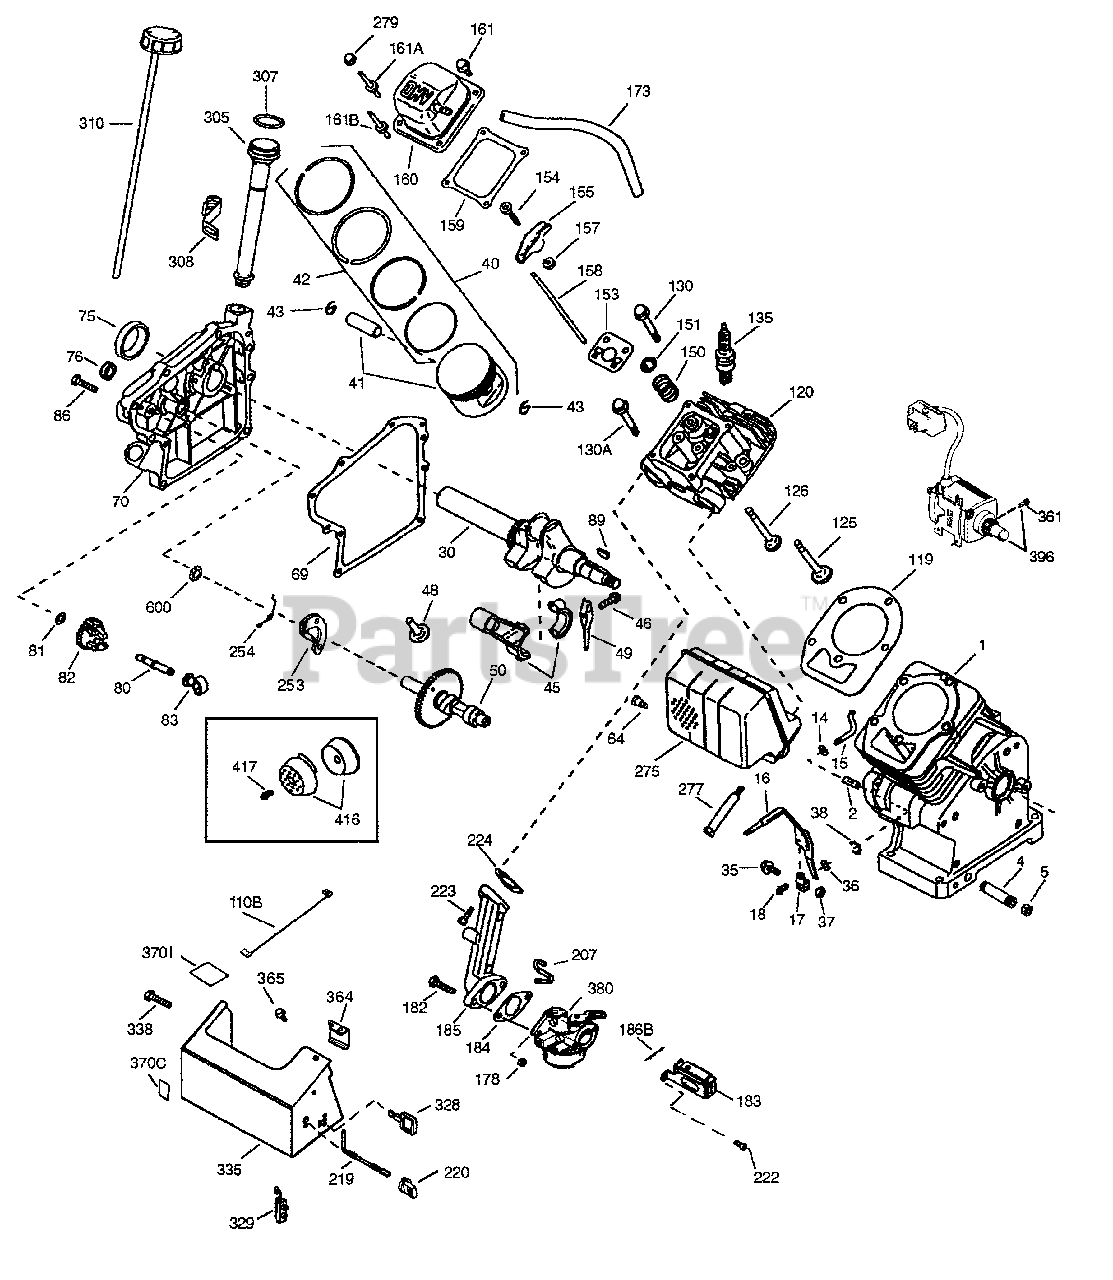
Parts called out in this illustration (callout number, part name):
1	Cylinder
2	Dowel Pin
4	Oil Drain Extension
5	Extension Cap
15	Governor Rod
16	Governor Lever
17	Governor Lever Clamp
18	Screw, Torx T-15, 8-32 x 3/8"
30	Crankshaft
35	Screw, 10-32 x 3/4"
36	Lock Washer
37	Lock Nut, 10-32
38	Retaining Ring
40	Piston, Pin & Ring Set (Standard)
41	Piston & Pin Ass'y (Standard)
42	Ring Set (Standard)
43	Piston Pin Retaining Ring
45	Connecting Rod Ass'y
46	Connecting Rod Bolt
48	Valve Lifter
49	Oil Dipper
64	Screw, 1/4-20 x 27/32"
69	Cylinder Cover Gasket
70	Cylinder Cover
76	Camshaft Seal
80	Governor Shaft
82	Governor Gear Ass'y
83	Governor Spool
86	Screw, 1/4-20 x 1-1/4"
89	Flywheel Key
110B	Ground Wire
119	Cylinder Head Gasket
120	Cylinder Head
125	Exhaust Valve (Standard)
126	Intake Valve (Standard)
130	Screw, 5/16-18 x 1-1/2"
130A	Screw, 5/16-18 x 2-41/64"
135	Resistor Spark Plug (N4C)
150	Valve Spring
151	Valve Spring Cap
153	Push Rod Guide
154	Rocker Arm Stud
155	Rocker Arm
157	Nut, 1/4-28
159	Rocker Arm Cover Gasket
160	Rocker Arm Cover
161	Screw, 1/4-20 x 31/64"
173	Breather Tube
178	Nut, 1/4-20
182	Screw, 1/4-20 x 1"
183	Choke Bracket
184	Carb. to Intake Pipe Gasket
185	Intake Pipe
186B	Choke Spring
207	Throttle Link
219	Choke Rod
220	Choke Knob
222	Screw, 10-32 x 1/2"
223	Screw, 1/4-20 x 1"
224	Intake Pipe Gasket
253	Compression Release Weight
254	Compression Release Spring
275	Muffler
277	Screw, 1/4-20 x 2-9/32"
279	Nut & Lock Washer
305	Oil Fill Tube
308	Fill Tube Clip
328	Ignition Key
335	Carburetor Cover
338	Screw, 10-32 x 1/2"
361	Screw, 1/4-20 x 5/8"
364	Carburetor Cover Bracket
365	Screw, 10-32 x 1/2"
370C	Primer Decal
370I	Warning Decal
380	Carburetor Ass'y
396	Electric Starter Motor (110 Volt)
416	Spark Arrestor Kit
417	Screw, 8-32 x 3/8"
